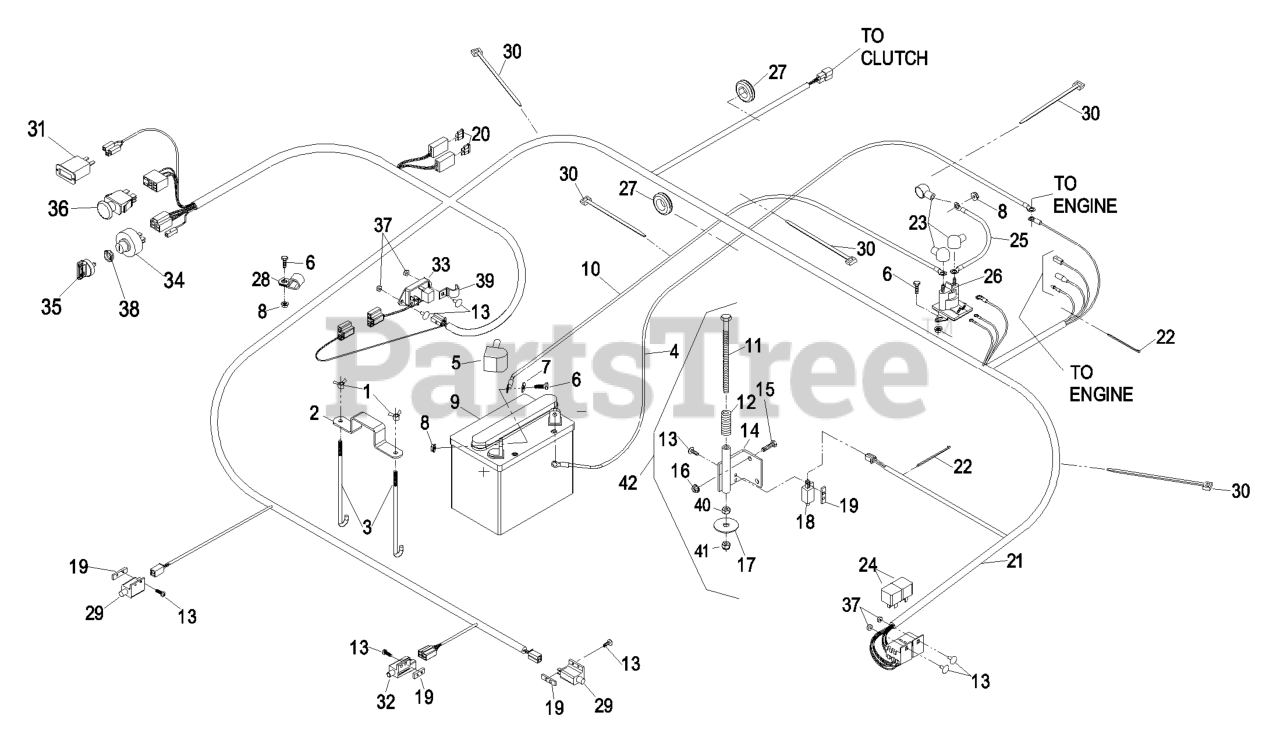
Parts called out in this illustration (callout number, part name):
1	WINGNUT
2	STRAP-HOLDDOWN
3	BOLT-HOLDDOWN
4	CABLE-GROUND, NEGATIVE
6	SCREW-HH
7	WASHER-FLAT
11	SCREW-HH
12	SPRING-SWITCH, SEAT
13	SCREW-PPH
14	BRACKET-SWITCH, SEAT
15	SCREW-HH
18	SWITCH-CLOSED, NORMALLY
19	PLATE-TAPPED
20	FUSE-BLADE TYPE, 20 AMP
22	TIE-CABLE
23	INSULATOR-SOLENOID
27	GROMMET
28	CLIP-LOOM
29	SWITCH-OPEN, NORMALLY
30	TIE-PLASTIC
31	METER-HOUR
33	MODULE-DELAY, SEAT
35	KEY-IGNITION
37	NUT-LOCK, NI
38	NUT-SWITCH, IGNITION
39	CLIP-HALF, LOOM
40	NUT-HEX
41	NUT-LOCK, NI
42	ASM,SEAT SWITCH ACTUATOR
